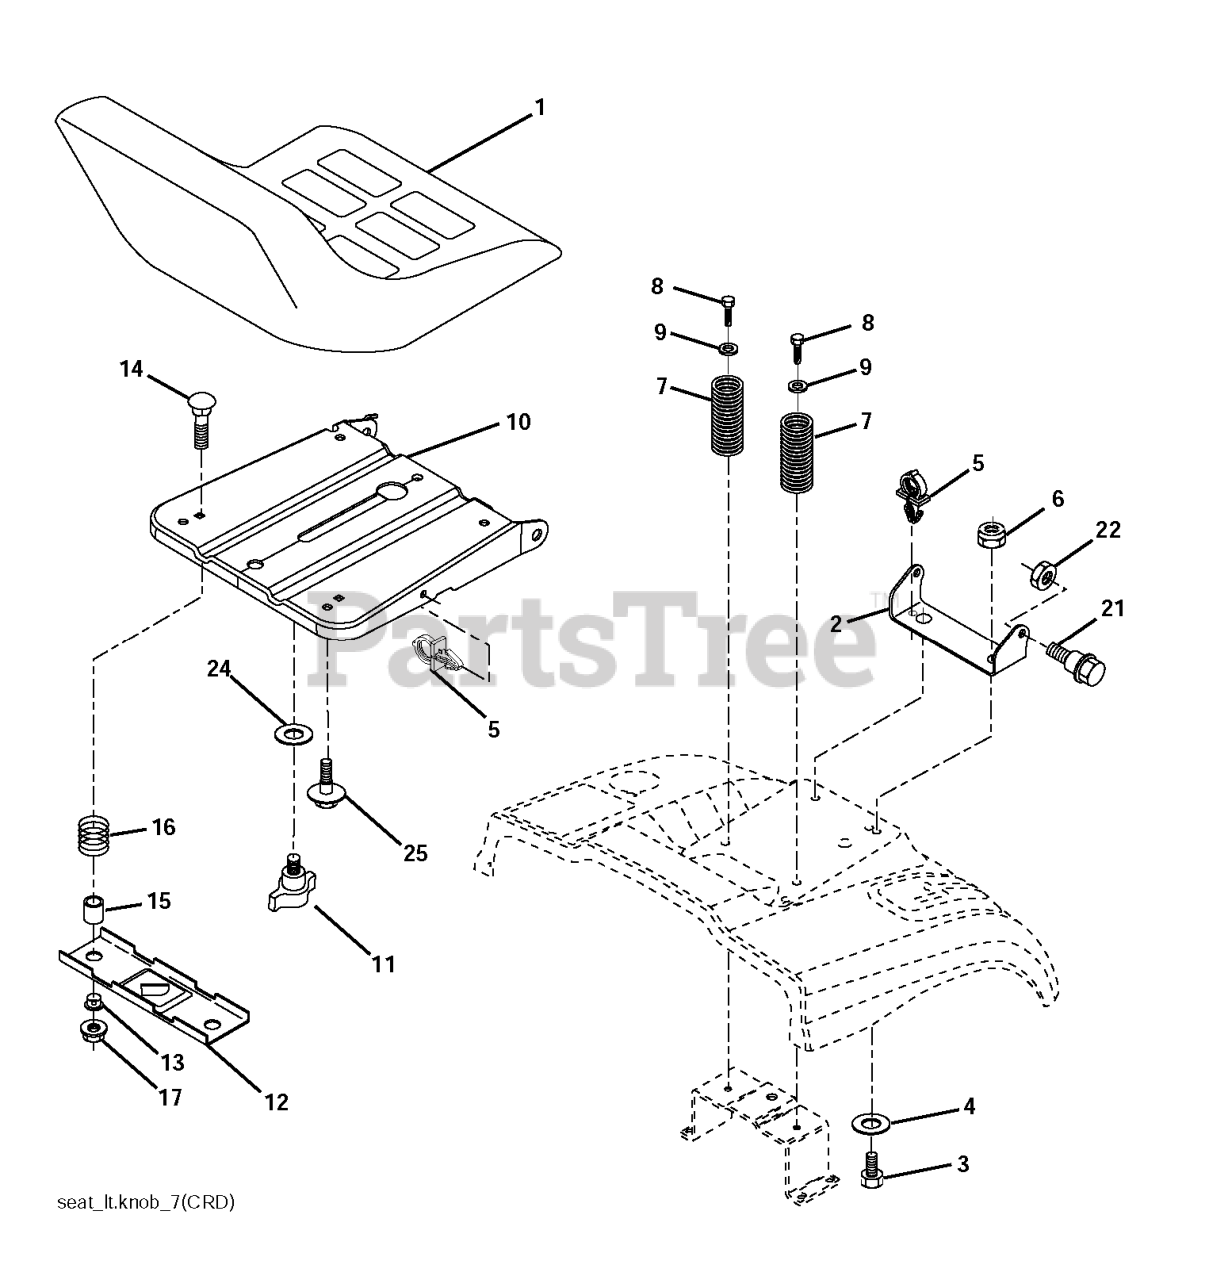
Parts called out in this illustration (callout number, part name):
1	RP SEAT
2	SEAT PIVOT BRKT
3	BOLT, HEX 3/8-16X1
6	NUT
7	SPRING COMPRESSION
8	SCREW 3/8-16X1
9	WASHER
10	PAN.ASM.SEAT.1SLOT
11	KNOB.SEAT.ADJ.WINGNUT
12	BRKT.MNTNG.SWITCH.SEAT.BLACK
14	BOLT.ROUND.HEAD.SQUARE.NECK
15	SPACER SPLIT 28X.96
17	NUT T
21	BOLT.SHOULDER.5/16-18
22	NUT.71038.31-18.HEX.NYLOCK
25	BOLT,SHOULD
